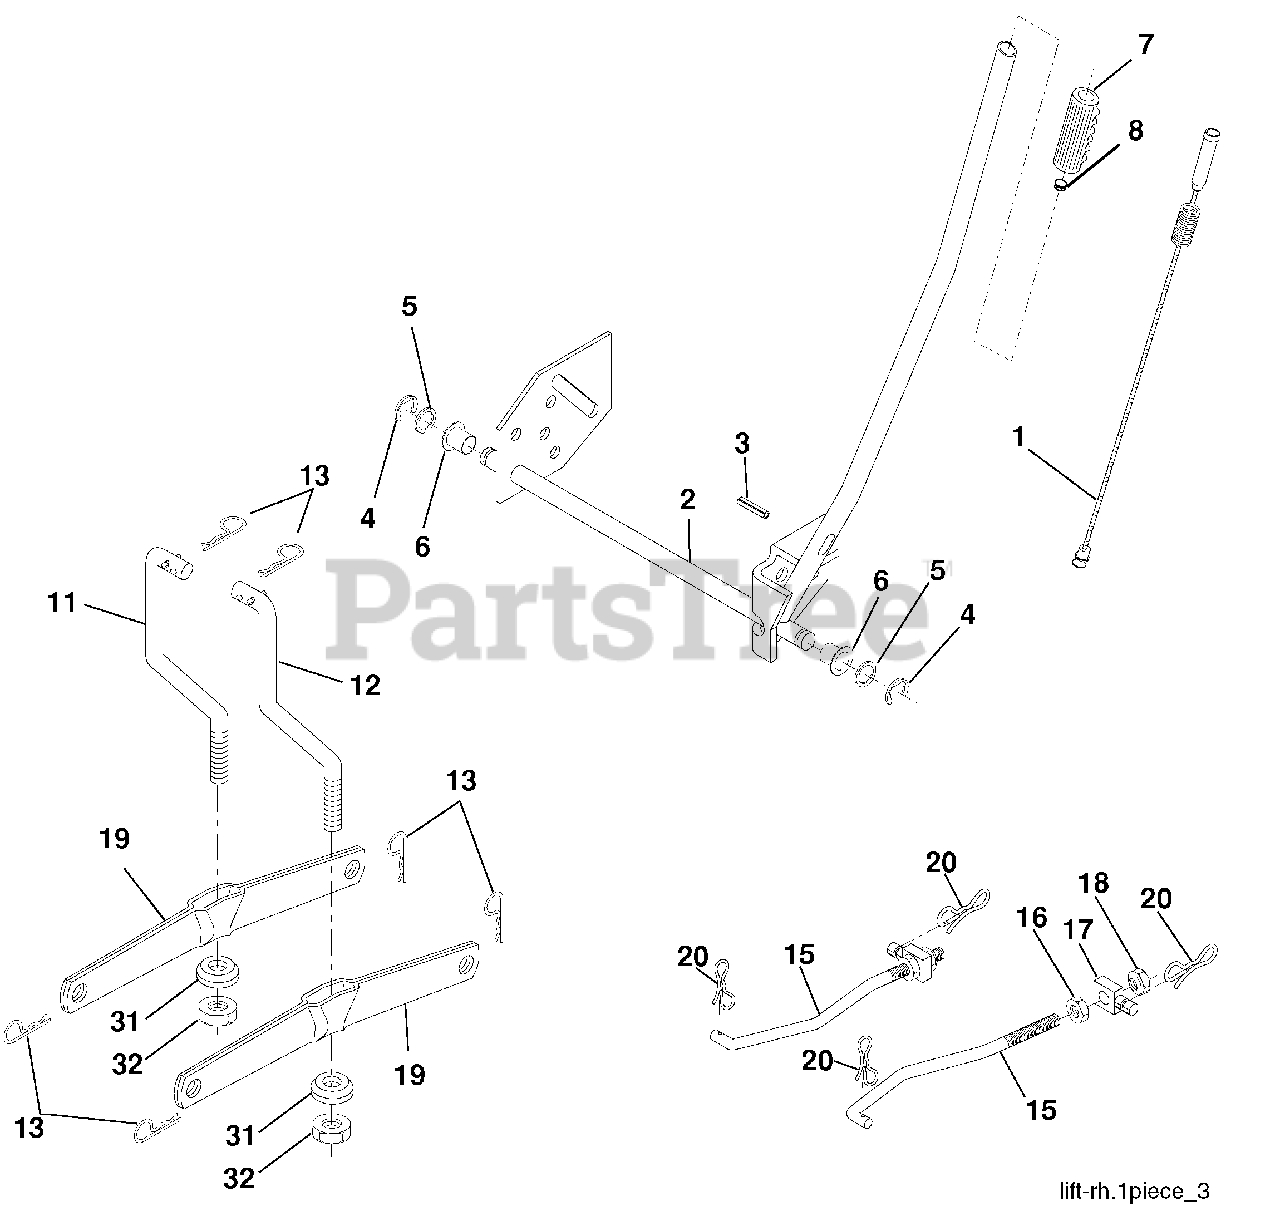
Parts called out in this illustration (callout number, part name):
1	Wire Asm Inner/Sprg w/plunger
2	Shaft Asm Lift RH
3	Pin Groove 1 500 Zinc
4	E Ring #5133-62
5	Washer 21/32 x 1 x 21 Ga.
6	Bearing Nylon Blk 629 Id
7	Grip Handle Bicycle Matte Blk
8	Button Plunger Black
11	Link Lift LH Fixed Length
12	Link Lift RH Fixed Length
13	Retainer Spring
15	Link Front
16	Nut Jam Hex 1/2-13 unc
17	Trunnion
18	Nut Lockw/Wsh 1/2-13 unc
19	Arm Suspension Rear
20	Pin Cotter 7/16 Bow Tie Lock
31	Bearing Pvt Lift
32	Nut Crownlock 3/8-24
